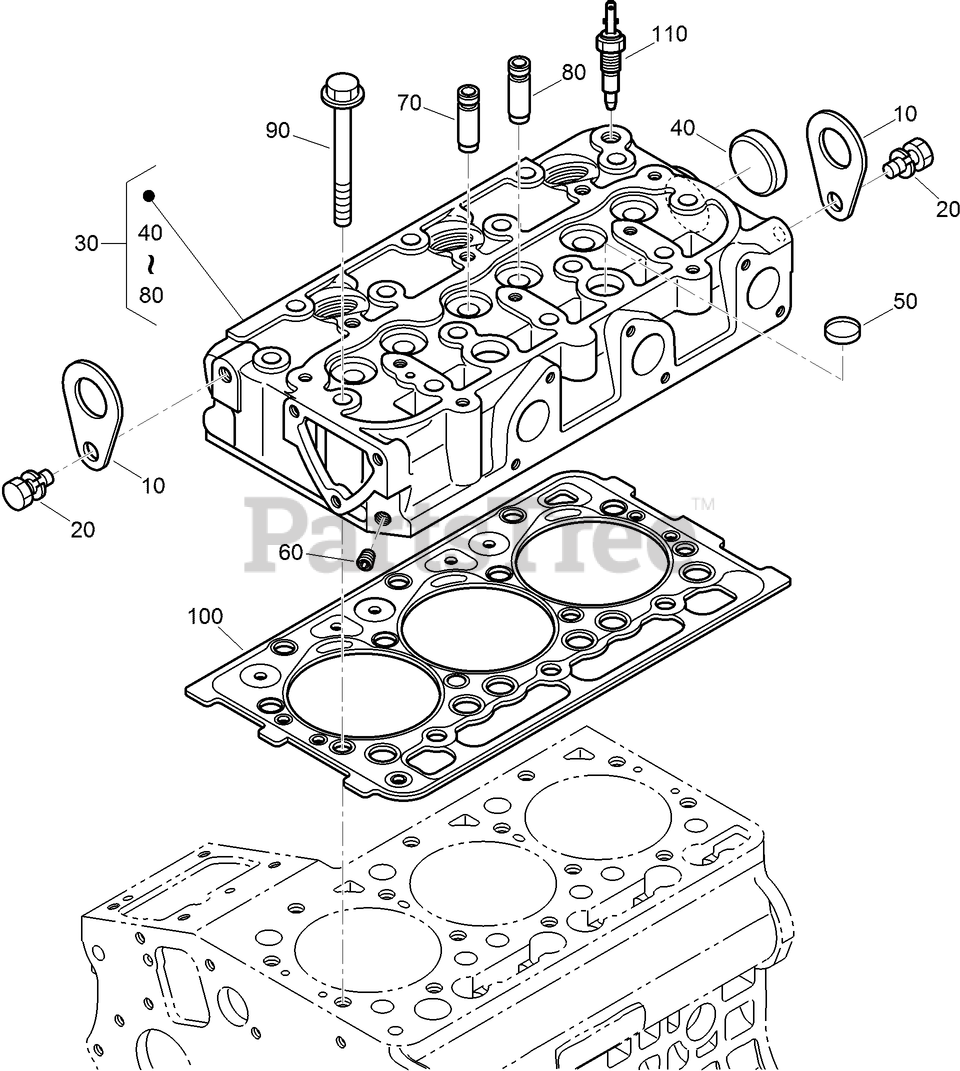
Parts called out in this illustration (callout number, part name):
10	HOOK-ENGINE
30	CYLINDER HEAD ASM
40	CAP-SEALING
50	CAP-SEALING
70	GUIDE-VALVE, INLET
80	GUIDE-VALVE, EXHAUST
90	BOLT-HEAD, CYLINDER
100	GASKET-HEAD, CYLINDER
110	THERMOSWITCH
